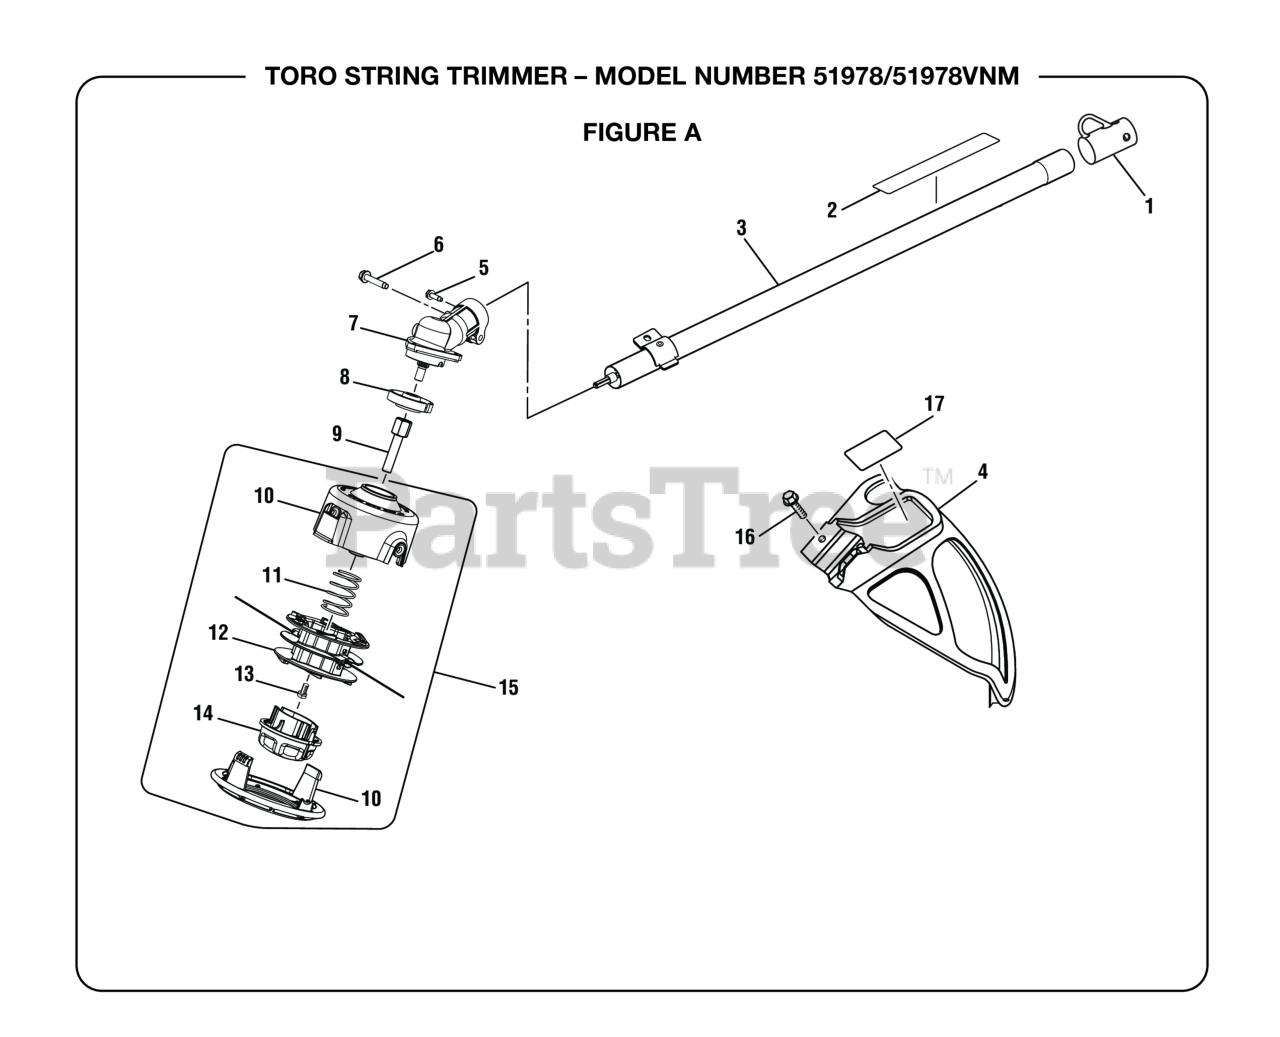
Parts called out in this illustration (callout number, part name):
1	Hanger Cap
2	Warning Icon Label
3	Straight Shaft Assembly
4	Grass Deflector Assembly
5	Screw w/Washer (10-24 x 5/8 in., Hex Hd. T.F.)
6	Screw (1/4-20 x 1-1/4 in., Hex Washer Hd. S.T.)
7	Gear Head Assembly
8	FLANGED WASHER
9	Trimmer Head Shaft Adaptor
10	Stringhead Housing
11	Compression Spring
12	Spool w/ Line (.095)
13	Screw (5/16 x 1/2 in., Left Hand)
14	Bump Knob
15	Trimmer Head Assembly (.095)
16	SCREW (#1/4-20 X 1-1/4 in. HEX WASHER HD.)
17	Grass Deflector Label
